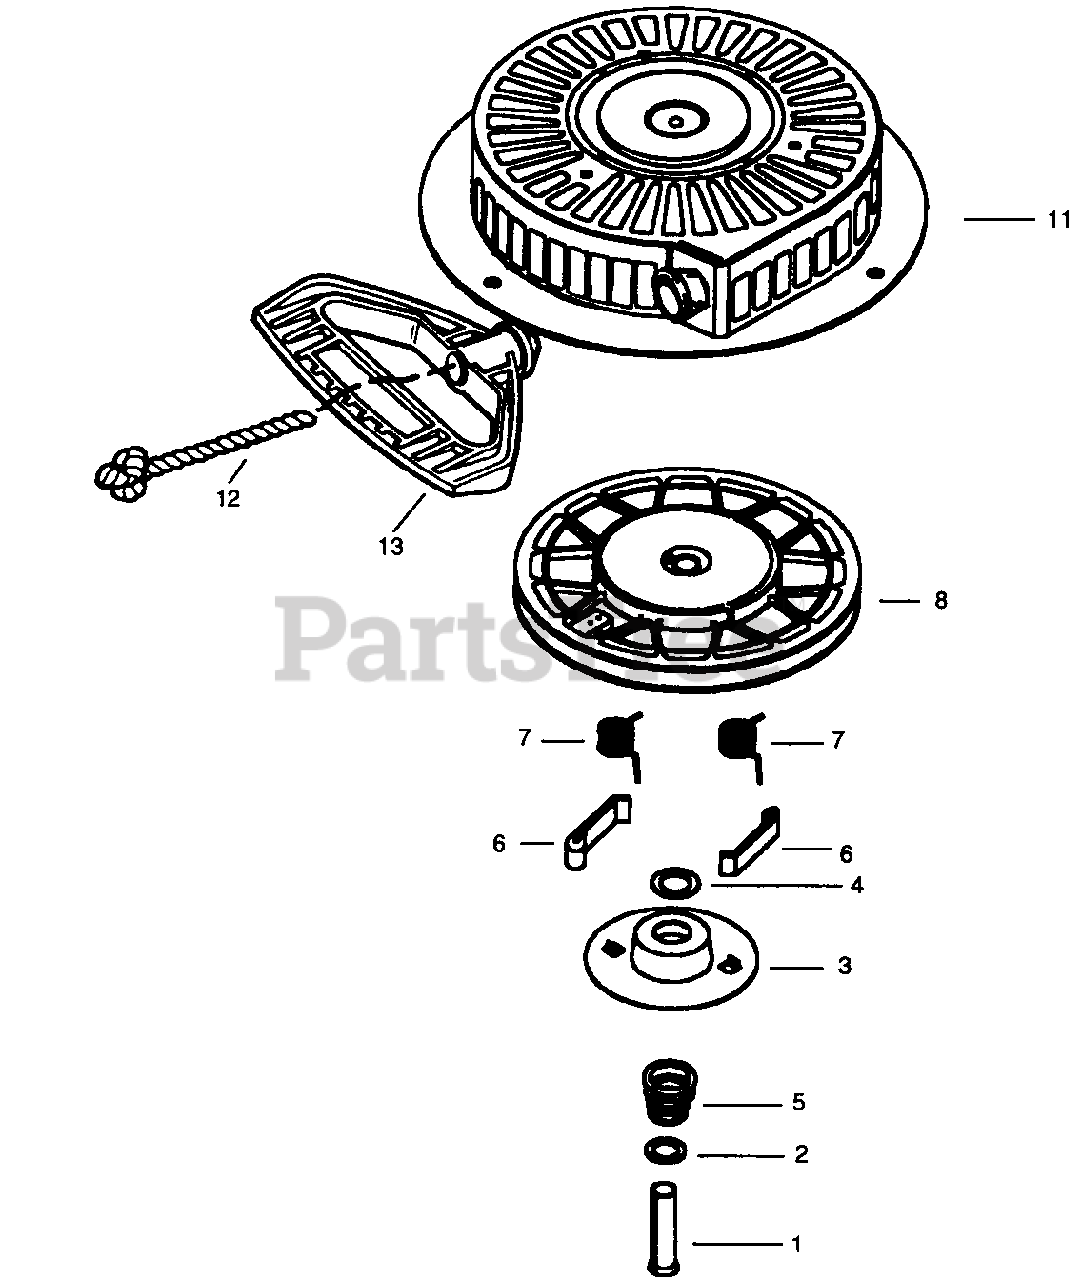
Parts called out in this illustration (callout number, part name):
1	Spring Pin
5	Brake Spring
6	Starter Dog
7	Dog Spring
8	Pulley & Rewind Spring Ass'y
11	Starter Housing Ass'y.
12	Starter Rope (Length 98" x 9/64" dia.)
13	Mitten Grip Handle
